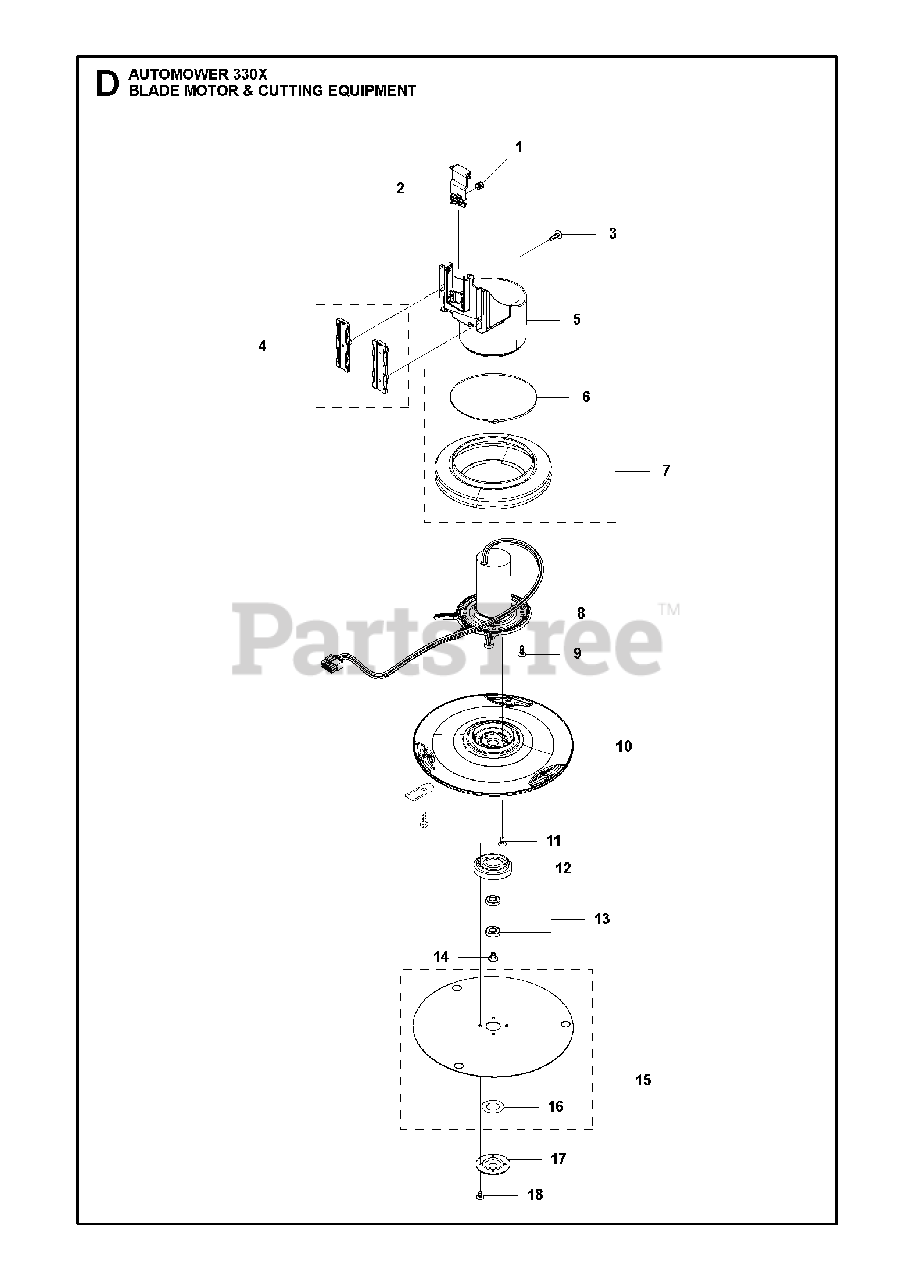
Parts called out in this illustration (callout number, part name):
1	SPRING LINK
2	LINK MOTOR HOUSING
3	SCREW 14MM
4	BEARING KIT
5	HOUSING CUTTING MOTOR
9	SCREW 14MM
11	SCREW
16	GASKET
17	COVER SKID PLATE
18	SCREW SILVER 10MM
